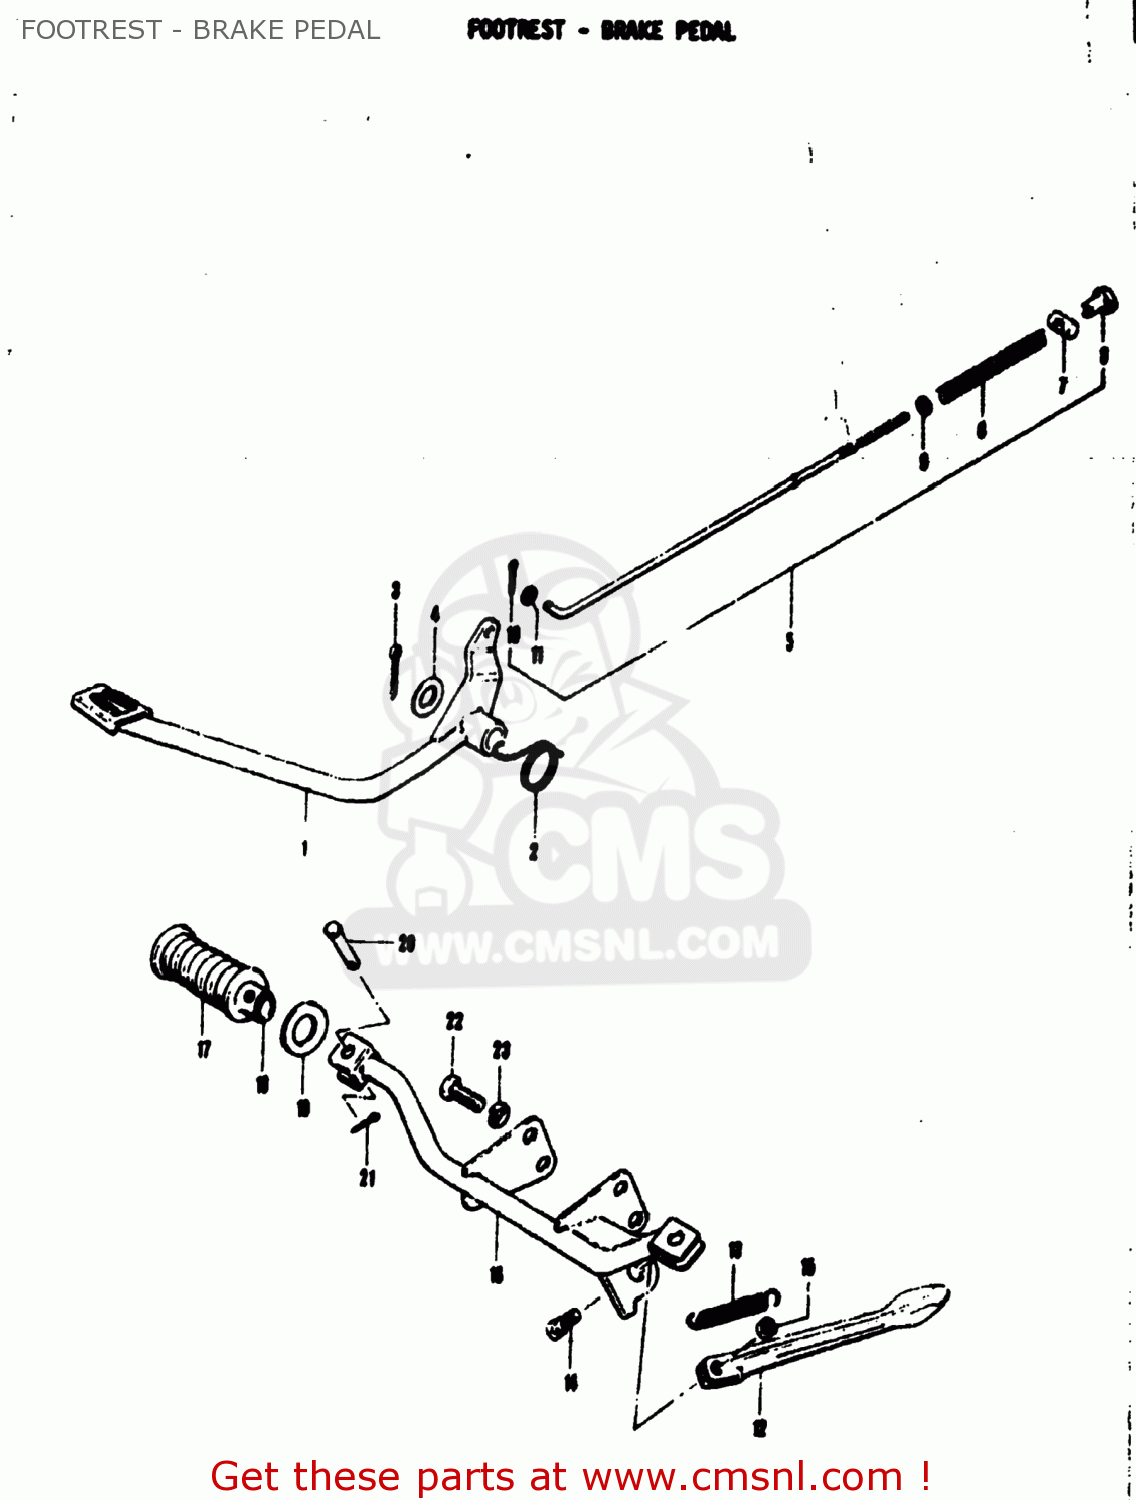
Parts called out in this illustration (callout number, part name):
1	PEDAL,BRAKE
2	SPRING
3	COTTER PIN
4	WASHER(15.5X26X2.3)
6	SPRING
7	PIN,10X19
8	NUT
9	WASHER
10	PIN 20X20
11	WASHER
12	STAND,SIDE
13	SPRING
14	BOLT
15	NUT
17	RUBBER,PILLION FOOTREST
18	BAR,FOOTREST RUBBER
19	WASHER
20	PIN
21	PIN 20X20
22	BOLT
23	LOCK WASHER
